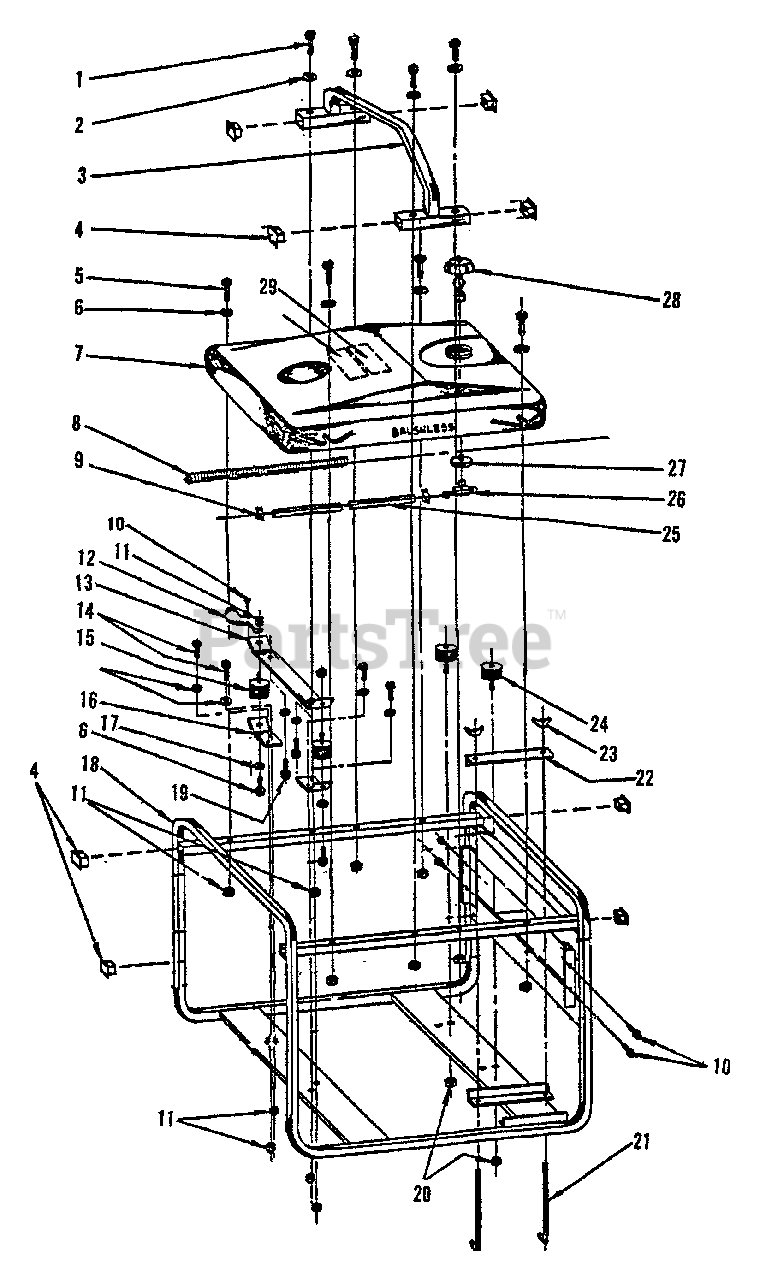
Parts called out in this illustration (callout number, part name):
1	5/16-18X2.5 HHS
2	LOCKWASHER - 5/16"
3	HANDLE, LIFTING
4	PLUG, END
5	BOLT - 5/16-18 X 1-1/2"
6	LOCKWASHER - 5/16"
7	TANK, FUEL - 6 GALLON
8	CONDUIT - 12"
9	CLAMP - 1/4"
10	SCREW - 10-24
11	LOCKNUT - 5/16-18
12	STRAP - GROUND
13	RAIL, FOCUS
14	5/16-18X7/8 HHS
15	ISOLATOR, VIBRATION
16	BRACKET, FOCUS
17	5/16-18X5/8 HHS
18	FRAME
19	5/16-18X3/4 HHS
20	LOCKNUT - 3/8-16
21	BOLT, BATTERY HOLD DOWN
22	BRACKET, BATTERY
23	WINGNUT - 1/4"
24	ISOLATOR, VIBRATION
25	LINE, FUEL - 24"
26	VALVE, FUEL TANK
27	GROMMET
28	CAP ASSY
29	LABEL - SAFETY
